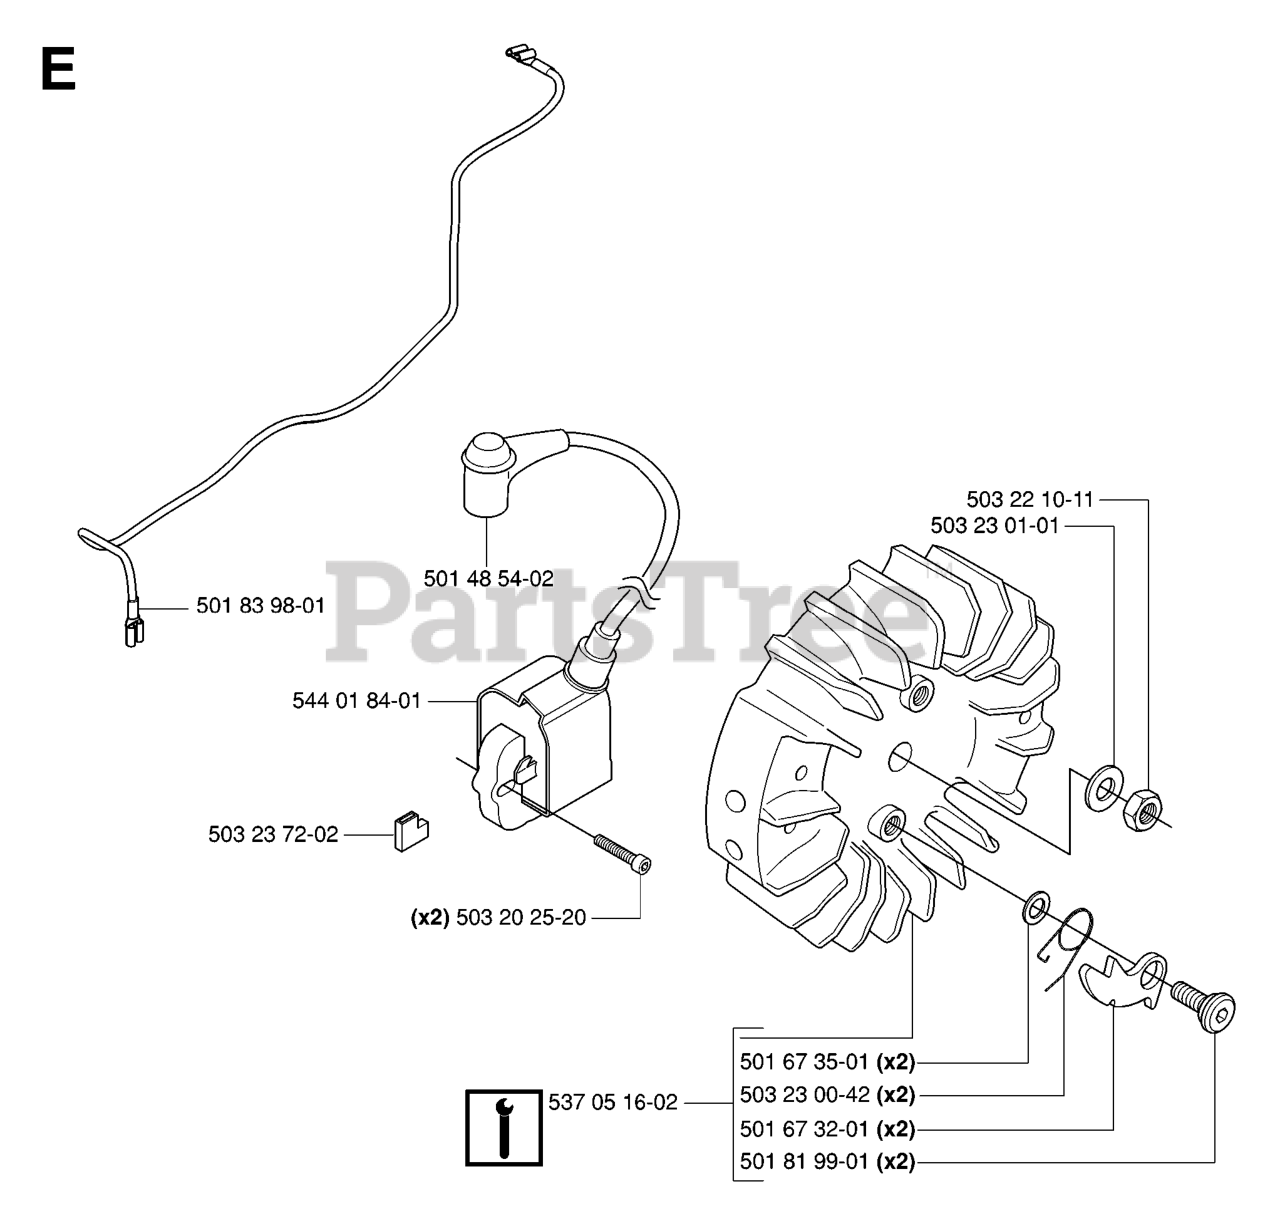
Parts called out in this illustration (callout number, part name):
1	WHEEL, LEFT
2	WHEEL, RIGHT
3	FRONT DECK PLATE, LEFT
4	FRONT PLATE, LEFT
5	FRONT DECK PLATE, RIGHT
6	FRONT PLATE, RIGHT
7	SHOULDER BOLT
9	WASHER, 3/8 SPEC
10	WHEEL PLATE, FRONT
11	AXLE WASHER
13	SLW 3/8 STD
14	NUT 5/16C CENTERLOCK
15	FLAT WASHER 5/16 SAE
16	HCS 3/8-16X1.GRD.5.ZD
17	CARRIAGE BOLT 5/16C X 5/8"
18	TIRE, 9" RIGHT
19	TIRE 9" LEFT
20	BEARING, WHEEL
